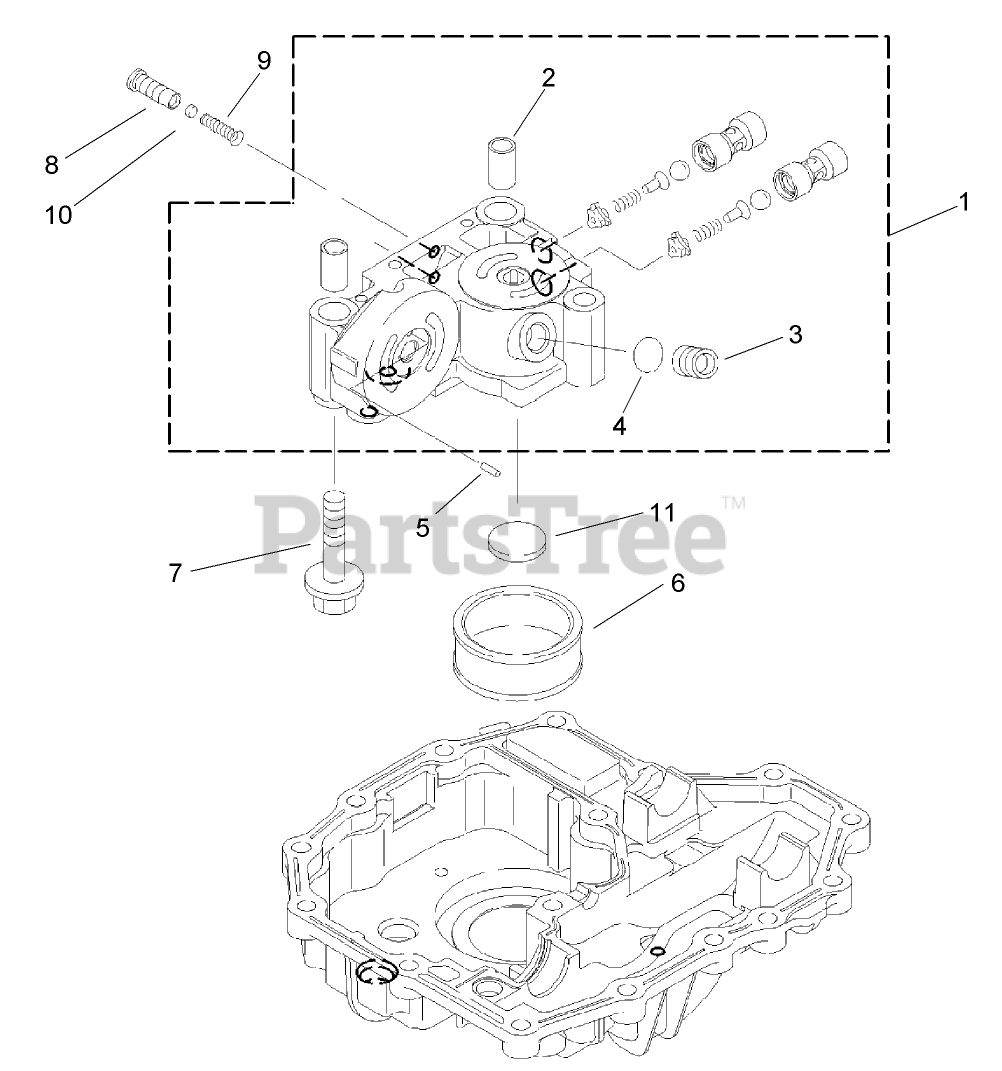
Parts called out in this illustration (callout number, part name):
2	PIN-KNOCK
4	PACKING
6	FILTER
9	SPRING
10	FILTER
11	MAGNET
